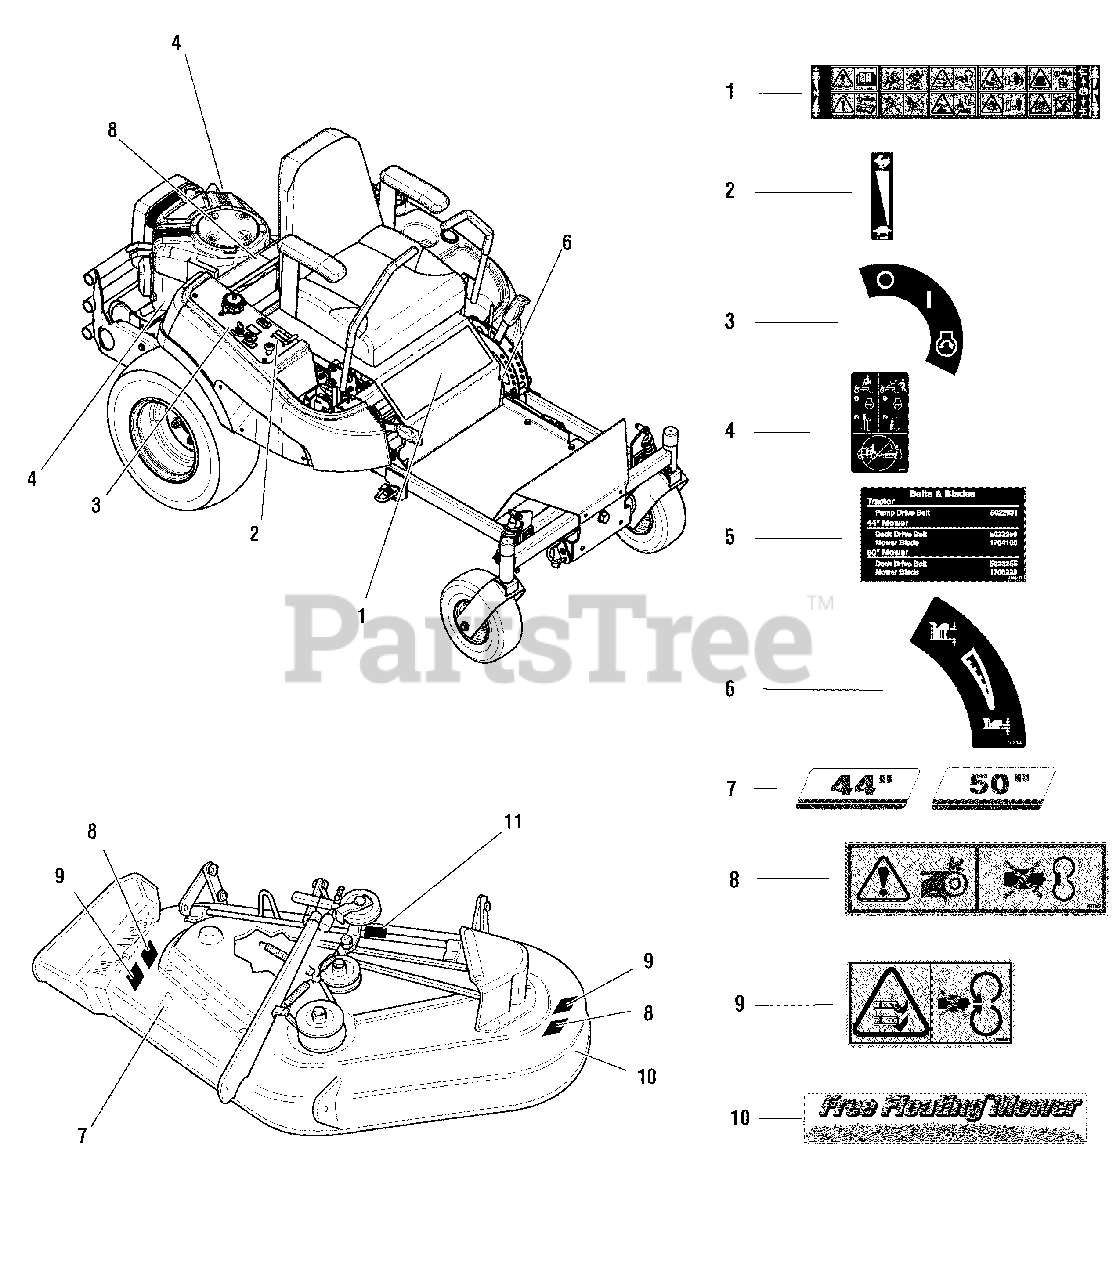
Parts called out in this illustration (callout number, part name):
1	DECAL, MAIN, CE
2	DECAL, THROTTLE CONTROL
3	DECAL, IGNITION SWITCH
4	DECAL, TRANSAXLE RELEASE
5	DECAL, BELT & BLADE, CONS Z
6	DECAL, HEIGHT OF CUT
7	DECAL-44"- SILVER ON BLACK W/STRIPE
7	DECAL-50"- SILVER ON BLACK W/STRIPE
8	DECAL, CE DANGER
9	DECAL-DANGER ROTATING BLADE SYMBOLS
10	DECAL-FREE FLOATING MOWER- SILVER
11	TAG, PRINTED SERIAL
12	DECAL, HYDRAULIC OIL, SAE 20W-50
